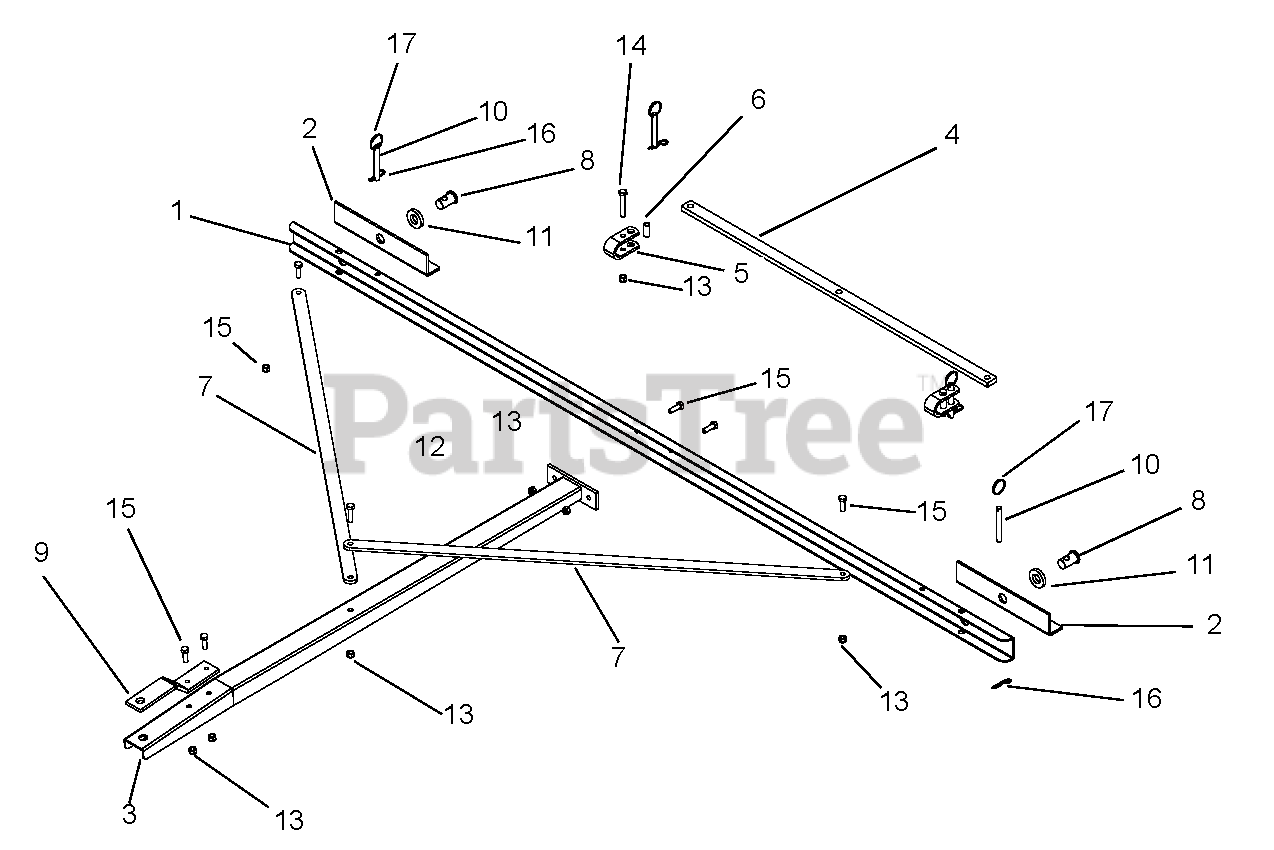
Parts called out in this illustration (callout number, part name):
10	2
11	2
12	1
13	9
14	2
16	2
